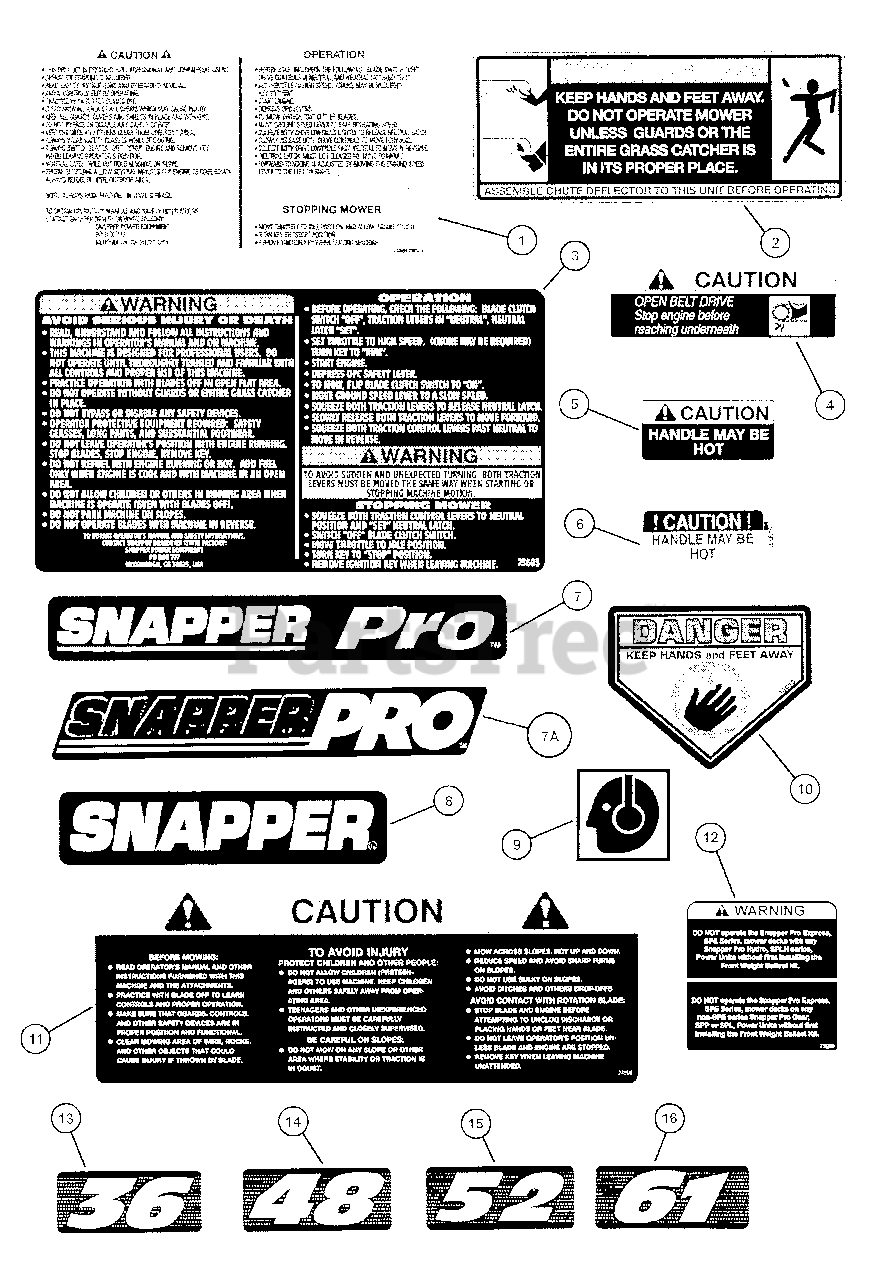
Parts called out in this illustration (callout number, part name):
1	DECAL, Caution/Operation, Pro Hydro
2	DECAL, Danger Guard/Catcher
3	DECAL, Warning/Operation Pro Hydro
4	DECAL, Caution, Open Belt Drive
5	DECAL, Caution, Adjustment Handle
6	DECAL, Caution Handle May Be Hot (Adjustable Decks only)
7	DECAL, Snapper Pro w/Trademark (white letters)
7	DECAL, Snapper Pro w/Trademark (silver letters)
7A	DECAL, Snapper Pro (silver, 16-1/2" long)
8	SNAPPER LOGO, 8" Molded-White
9	DECAL, Ear Protection
10	DECAL, Danger (CPSC) Cut Finger
11	DECAL, Caution- Operator Instruction
12	DECAL, Warning! Counterweight
13	DECAL, 36" Deck Commercial
14	DECAL, 48" Deck Commercial
15	DECAL, 52" Deck Commercial
16	DECAL, 61" Deck Commercial
